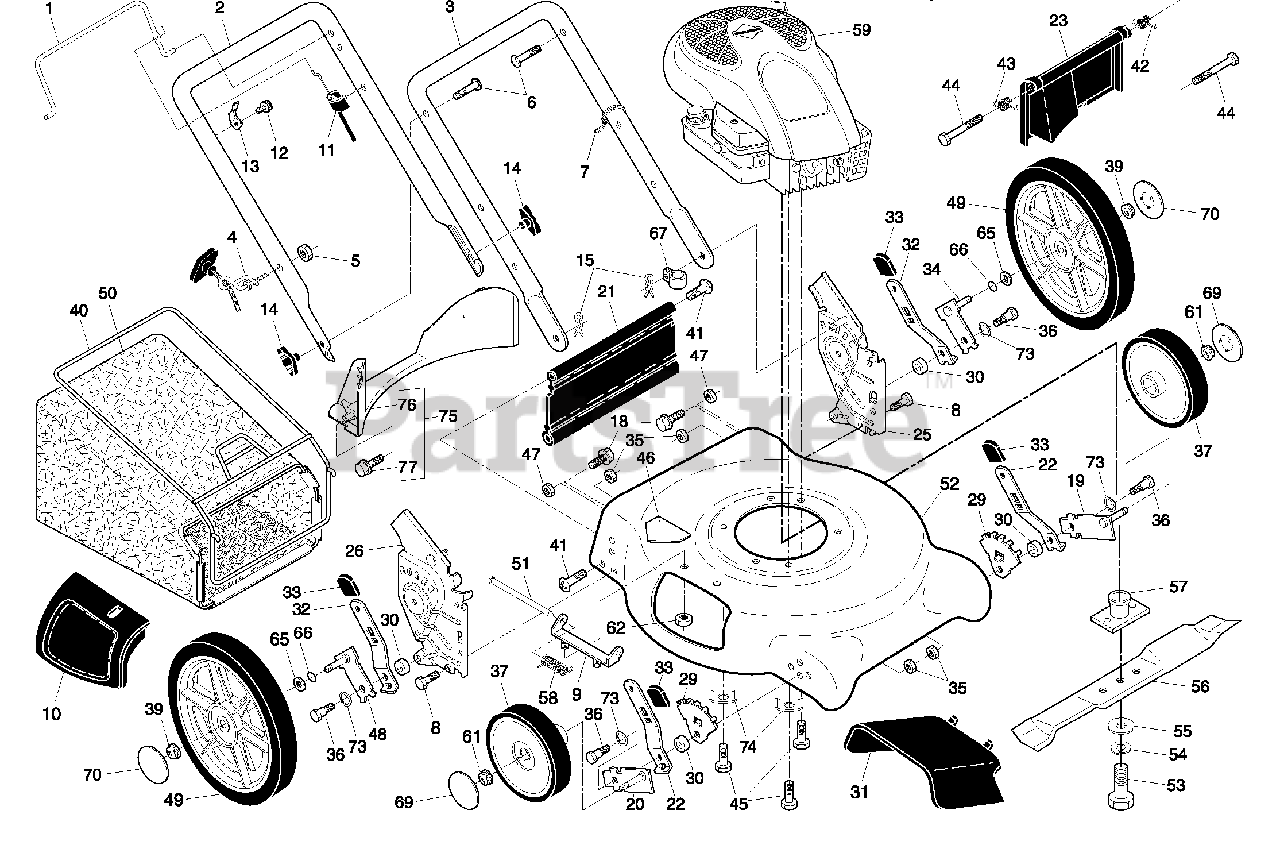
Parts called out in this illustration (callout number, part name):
1	Control Bar
2	Upper Handle
3	Lower Handle
4	Rope Guide
6	Handle Bolt
7	Wire Tie
8	Bolt, Hex Head 5/16-18 x 3/4
9	Hinge Bracket
10	Mulcher Door
11	Engine Zone Control Cable
12	Hex Washer Head Screw #10-24 x 1/2
13	Up-Stop Bracket
14	Handle Knob
15	Hairpin Cotter
18	Screw
19	Axle Arm Assembly, Front, LH
20	Axle Arm Assembly, Front, RH
21	Kit, Rear Skirt
22	Selector Spring, Front
23	Rear Door Assembly
25	Handle Bracket, LH
26	Handle Bracket, RH
29	Wheel Adjusting Bracket
30	Spacer
31	Discharge Deflector
32	Selector Spring, Rear
33	Selector Knob
34	Axle Arm Assembly, Rear, LH
35	Locknut, Hex 5/16-18
36	Shoulder Bolt 5/16-18
37	Wheel & Tire Assembly, Front 8 x 2
39	Nut, Hex
40	Frame, Grassbag
41	Screw, Hinge
42	Spring, LH
43	Spring, RH
44	Bolt, Rear Door
45	Hex Head Thread Rolling Screw 3/8-16 x 1
46	Danger Decal
47	Nut, Hex
48	Axle Arm Assembly, Rear, RH
49	Wheel & Tire Assembly, Rear 12 x 2
51	Hinge Rod
52	Kit, Housing
53	Screw, Hex Head, Grade 8 3/8-24 x 1-3/8
54	Helical Lockwasher
55	Hardened Washer
56	21" Blade
57	Blade Adapter
58	Hinge Spring
61	Flanged Locknut
62	Nut, Hex
65	Washer, Flat
66	O-Ring
67	Clip, Cable
69	Hubcap, Front Wheel
70	Hubcap, Rear Wheel
73	Washer, Curved, Cylindrical
74	Washer, Special, Engine
75	Kit, Rear Baffle
76	Baffle, Rear
77	Screw, Rear Baffle
77	Operator's Manual, English
77	Operator's Manual, French
77	Repair Parts Manual
